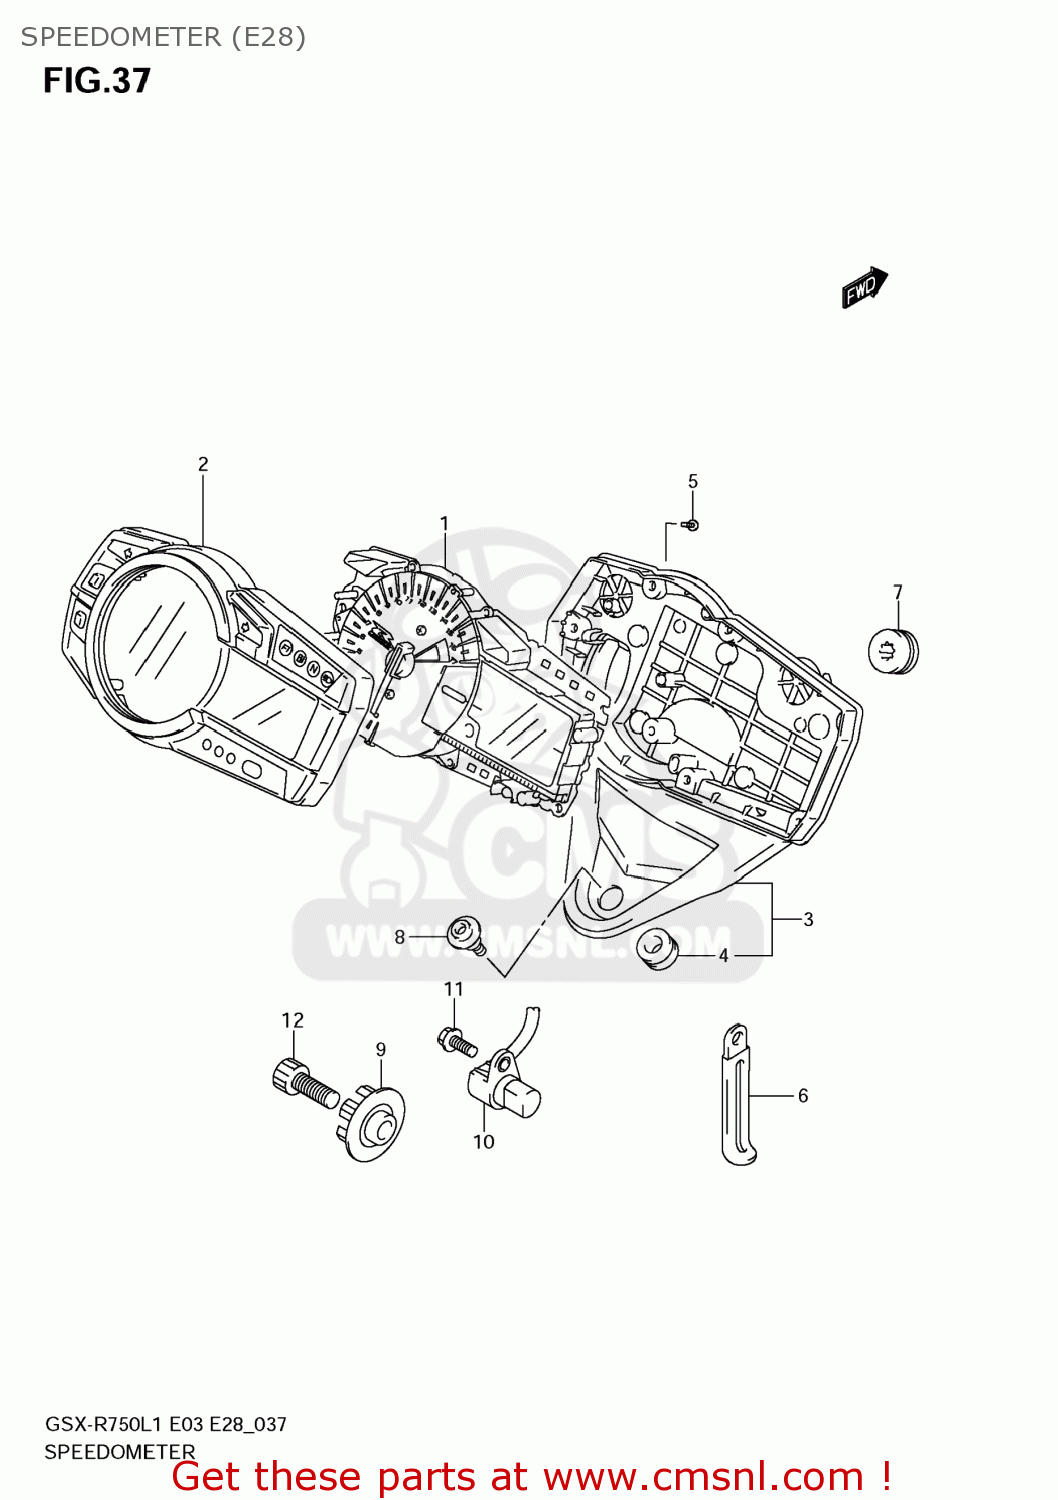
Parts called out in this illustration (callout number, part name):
1	SPEEDOMETER
2	CASE ASSY,UPR
3	LWR CASE ASSY
4	CUSHION,METER
5	SCREW(3X16)
6	CLAMP(L:45)
7	CUSHION
8	SCREW,SPEEDOMETER
9	ROTOR,SPEED
10	SENSOR,SPEED
11	BOLT
12	BOLT
